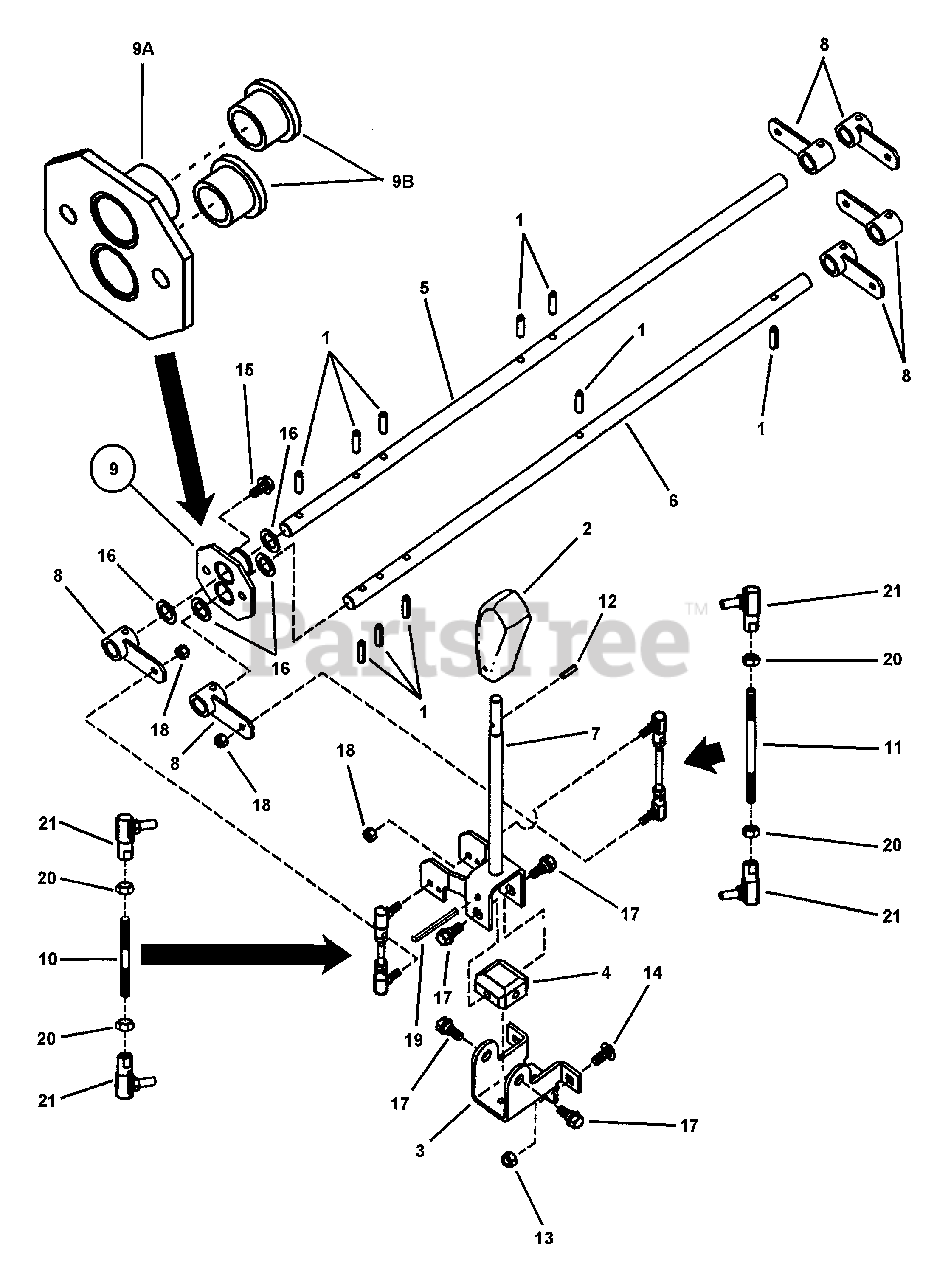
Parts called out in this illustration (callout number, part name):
1	ROLL PIN, 1/4 x 1"
2	HANDLE, Plastic
3	BRACKET, Joystick Mounting
4	BLOCK, Pivot Joystick Control
5	SHAFT, Upper Cross
6	SHAFT, Lower Cross
7	HANDLE, Joystick Control (Weldment)
8	ARM/HUB Weldment
9	ASSEMBLY, Cross Shaft Support
9A	SUPPORT, Cross Shaft (Weldment)
9B	BUSHING, Teflon Impregnated
10	ROD, Threaded 1/4-28 x 2.71 long
11	ROD, Threaded 1/4-28 x 3.85 long
12	ROLL PIN 3/16 x 3/4"
13	NUT, 5/16-18 HEX NYLON LOCK
14	BOLT, 5/16-18 x 3/4" Square Neck Carriage, Grade 5
15	SCREW, 5/16-18 x 5/8" Hex Washer Self-Tap
16	WASHER, 41/64 I.D. x 1" O.D. Flat
17	BOLT, 5/16-18 Shoulder
18	NUT, 1/4-28 Hex Nyloc
19	ROLL PIN, 1/4 x 2-3/4"
20	NUT, 1/4-28 Hex, Grade 5 or B
21	BALL-JOINT, 1/4-28 Thread
